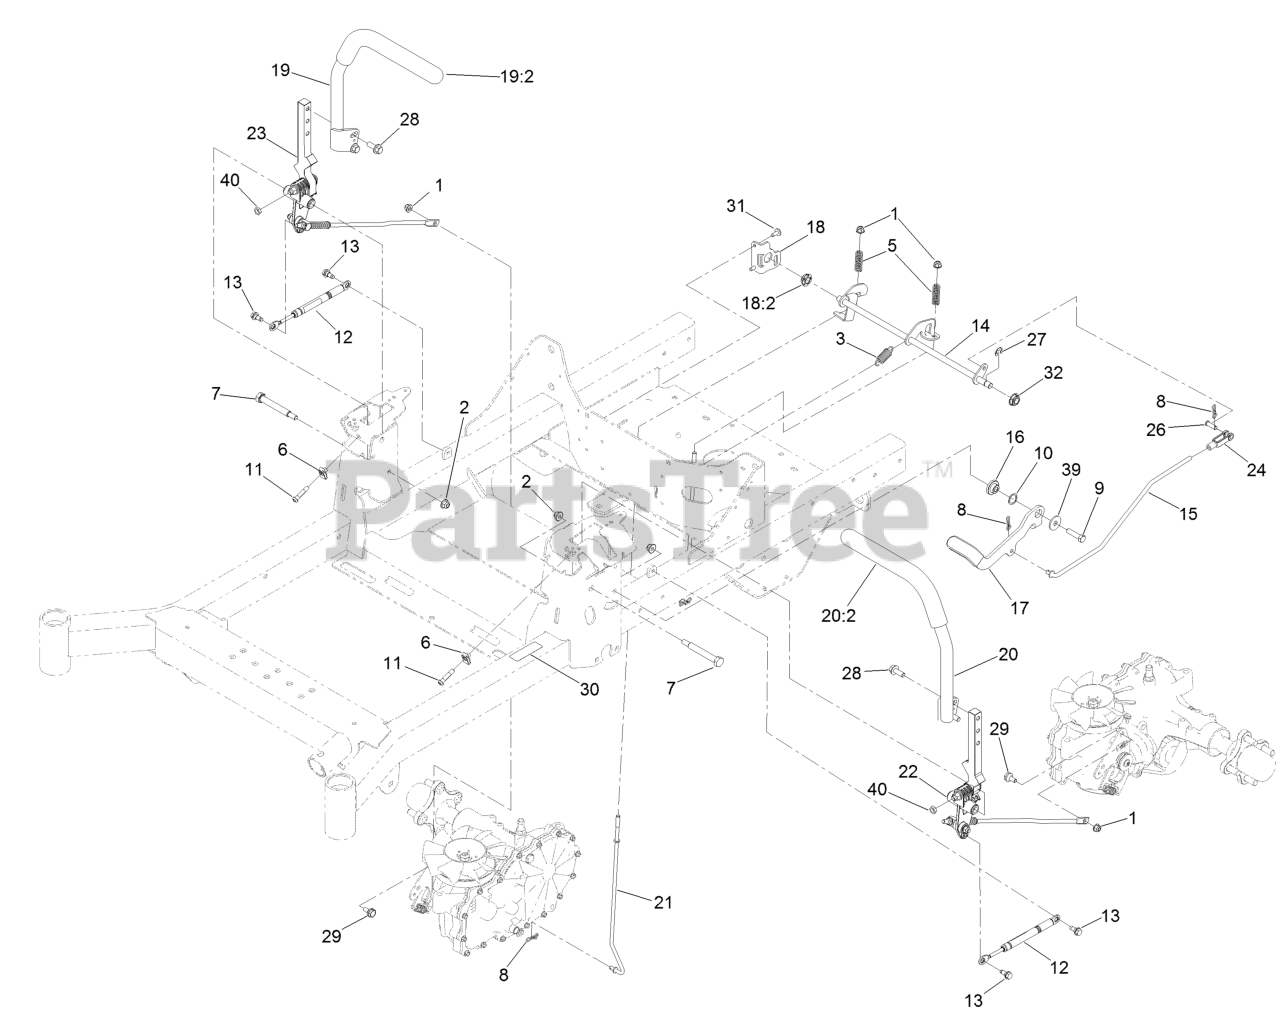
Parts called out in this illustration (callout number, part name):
1	Nut-HF, NI
2	Nut-HF, NI
3	Spring-Extension
5	Spring-Compression
7	Bolt-Pivot
8	Pin-Cotter, Locking
9	Screw-HH
10	Washer-Wave
11	Screw-HSBH
13	Screw-Shoulder
14	Shaft-Brake
15	Linkage-Brake, Upper
16	Pivot-Flange
17	Lever-Brake (With Grip)
18	Bracket-Brake
18:2	Bearing-Spherical
19	RH Control Handle ASM
20	LH Control Handle ASM
21	Linkage-Brake, Lower
22	LH Motion Control ASM
23	RH Motion Control ASM
24	Yoke-Adjustable
26	Pin-Clevis
27	Ring-Retaining, External
28	Screw-HHF
29	Bolt-Shoulder
30	Decal-Brake, Parking
31	Screw-Torx
32	Bearing-Spherical
39	Washer
40	Nut-Jam
